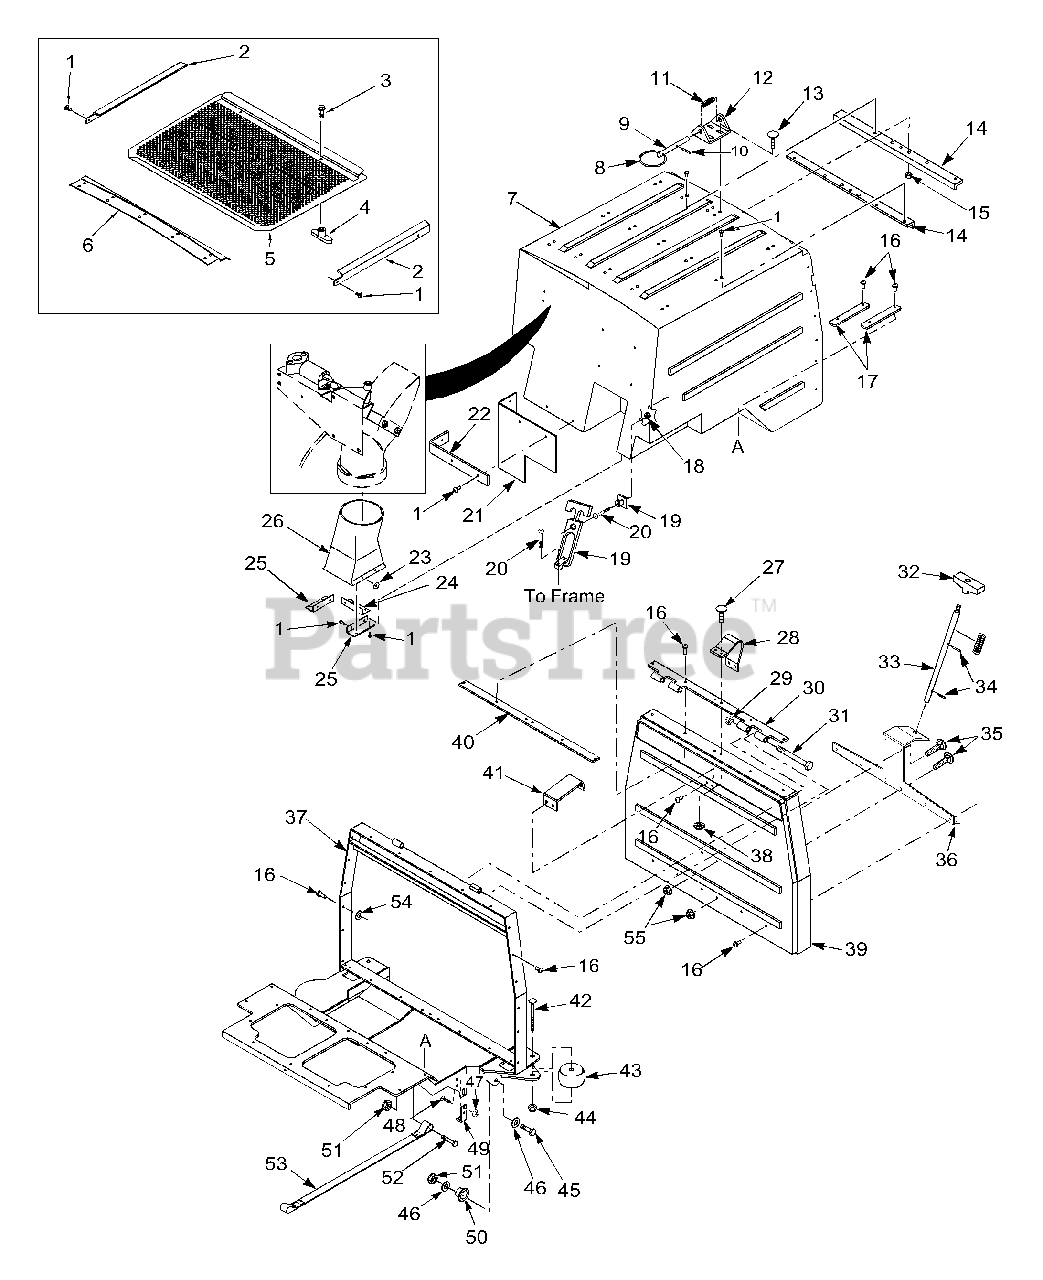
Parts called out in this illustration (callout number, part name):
1	Pop Rivet, 3/16 x .652
2	Guide Weldment, Screen
3	Bolt, Hex Head 5/16-18 x 3/4"
4	Plastic Knob, 5/16-18
5	Screen Weldment
6	Stop Weldment, Screen
7	Hopper
8	Split Ring
9	Pin, Hopper Latch
10	Roll Pin
11	Spring, Door Lock
12	Mount, Latch Pin
13	Bolt, Carr. 1/4-20 x 1"
14	Support, Hopper Top
15	Nut, Serr. Flange 1/4-20
16	Pop Rivet, 1/4 x .85
17	Retainer Strip, Hopper
18	Nut, Elastic Stop #10-32
19	Latch, Hopper
20	Screw, #10-32 x 1-1/2"
21	Pad, Rubber Heat Deflector
22	Backing PLate, Heat Deflector
23	Flatwasher, 1/4-.312 x .750 x .065
24	Mount, Transition Chute Rear
25	Mount, Transition Chute Side
26	Chute, Transition
27	Bolt, Carr. 1/4-20 x 1"
28	Latch, Hopper Door
29	Nut, Elastic Stop 5/16-18
30	Hinge Weldment, Hopper Door
31	Bolt, Hex Head 5/16-18 x 5-1/2"
32	Plastic Knob, 5/16-18
33	Pin, Hopper Door
34	Roll Pin, .188 x 1-1/2"
35	Bolt, Carr. 5/16-18 x 3/4"
36	Bracket, Door Latch
37	Hopper Frame Weldment
38	Nut, Serr. Flange 1/4-20
39	Door, Hopper
40	Backing Strip, Hinge
41	Backing Plate, Door Latch
42	Bolt, Carr. 3/8-16 x 4"
43	Wheel, Anti-Scalp
44	Lock Nut, 3/8-16
45	Bolt, Hex Head 3/8-16 x 1-3/4"
46	Flatwasher, 3/8-.391 x .938 x .105
47	Nut, Serr. Flange 1/4-20
48	Bolt, Carr. 1/4-20 x 3/4"
49	Bracket, Switch Mounting
50	Bushing, Hopper Pivot
51	Nut, Elastic Stop 3/8-16
52	Bolt, Hex Head 3/8-16 x 3-1/4"
53	Strap Bucket Stop
54	Flatwasher, 1/4-.258 x .50 x .0598
55	Nut, Serr. Flange 5/16-18
